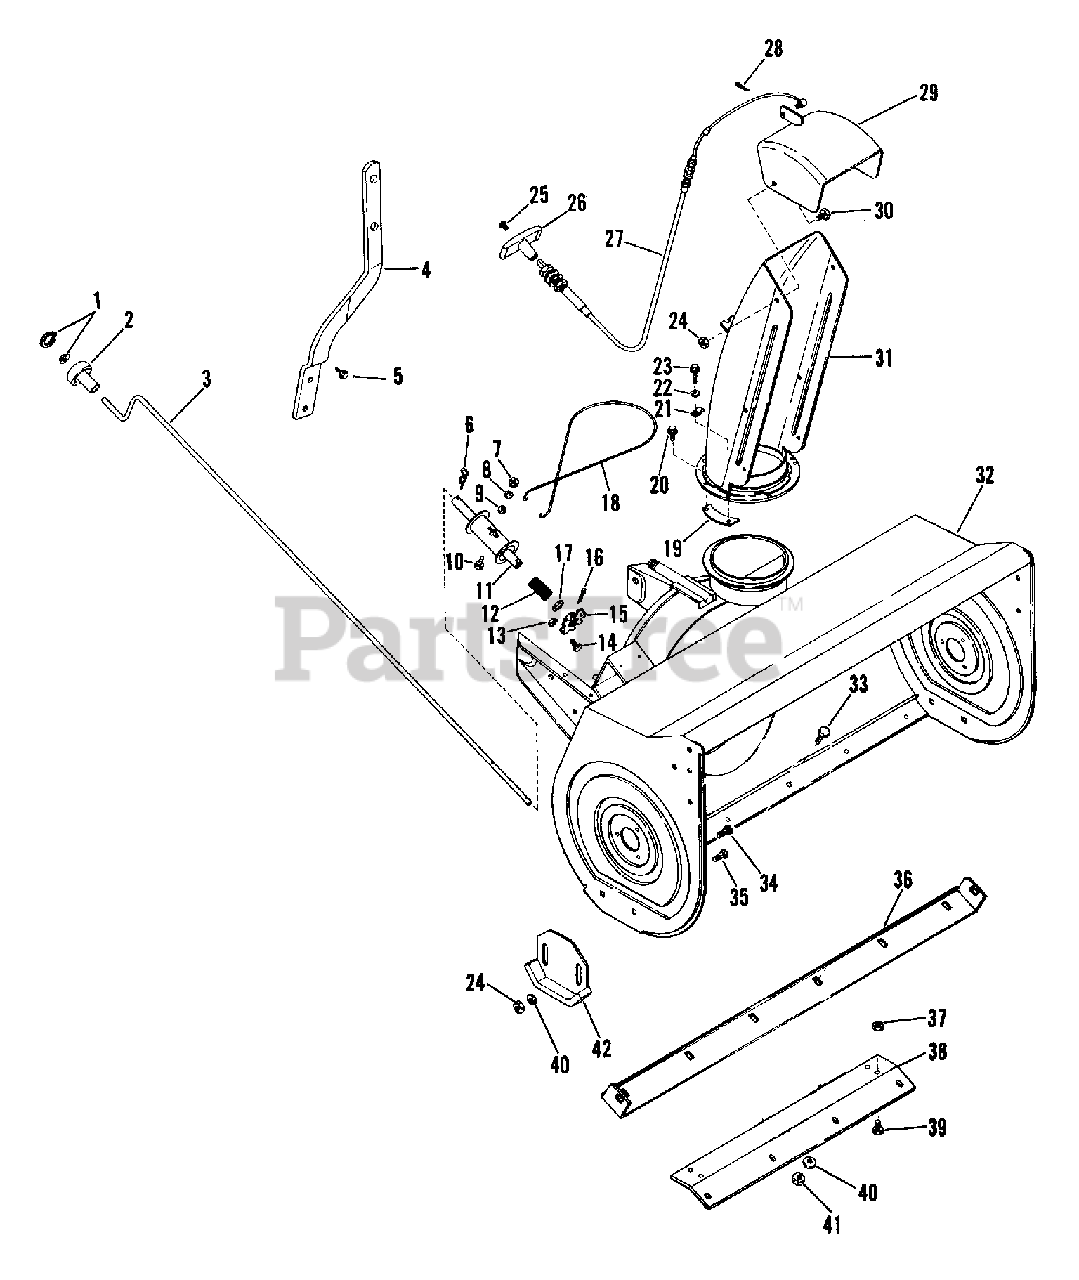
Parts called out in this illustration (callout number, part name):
1	CAP, 3/8 ROD YWZC
1	RG-RTNG-EXT .500X.015
1	NUT-LK-JAM-CTR .375-16 PL
2	KNOB
3	CRANK - CHUTE CONTROL
3	CHUTE CONTROL CRANK
4	CHUTE CRANK SUPPORT
5	SCR-TAP .312-18X1.0 HWH PL TR
6	PIN-HAIR INT .08X.38X1.42 YWZC
7	NUT-HEX .250-20 PL
8	WSHR-LK .313X.062
9	WSHR-FL-STL.281X.62X.065 PL
10	BLT-RDHDSQNK .25-20X.62 PL
11	SPOOL
12	SG-COMP .054X.75X1.6
13	NUT-LK DUAL FACE 10-24 PL
14	SCR-SKH 10-24X.38
15	DISC ASSEMBLY
16	PIN-ROLL .188X1.00
17	WSHR-FL-STL .640X1.005X.062 PL
19	CHUTE CLAMP
20	SCR-TAP 10-24X.375 CRPH PL 1A
21	CABLE CLAMP
22	WSHR-FL-STL .219X.500X.049 PL
23	SCR-TAP 10-24X.75 CRPH 1A
24	NUT-LK-CTR .375-16 GR A PL
25	SCR-MCH 10-32X.50 SLPAN SS
26	TEE HANDLE
27	CONTROL CABLE
28	PIN-COTR .09X.75 PL
29	DEFLECTOR W/DECAL
30	BLT-HEX .38-16X.75 PL GR2
31	DISCHARGE CHUTE
32	36 IN SNO-THRO HOUSING WITH DE
32	THROWER HOUSING W/DECALS
33	BLT-RDHDSQNK .31-18X.75 SHT PL
34	BLT-RDHDSQNK .38-16X.75 SHT PL
35	BLT-RDHDSQSHNK .38-16X1.00 PL
36	SCRAPER BLADE 36"
36	SCRAPPER BLADE
37	NUT-LK TOP .375-16 GR C YWZC
38	BLADE BRACE
38	SCRAPER BLADE BRACE
39	BLT-HEX .38-16X.75 PL GR5
40	WSHR-FL-STL .38X.875X.083 PL
41	NUT-LK .312-18 GR A PL
42	RUNNER-SKID SHOE
